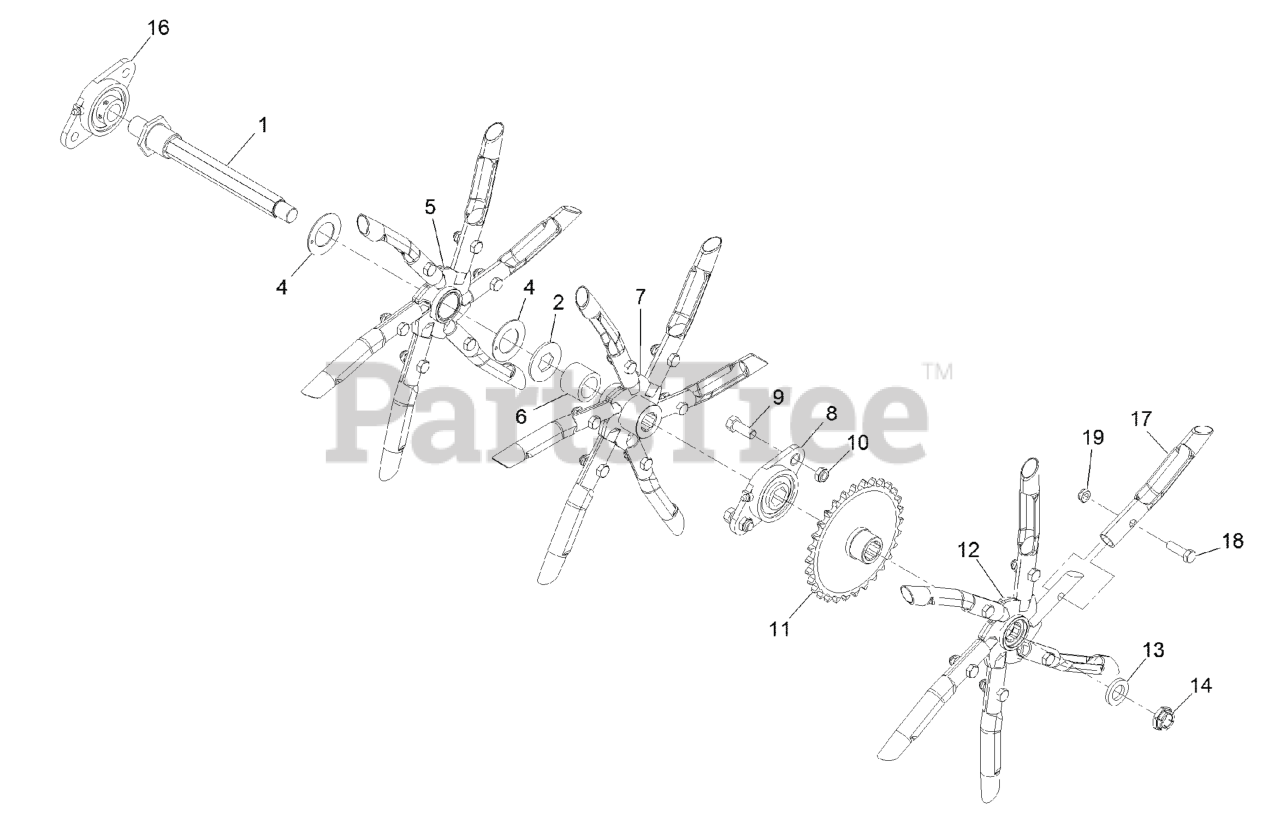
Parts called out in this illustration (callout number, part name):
1	TINE SHAFT ASM
2	KEEPER-TINE, FLOATING
4	WASHER-THRUST
5	FLOATING SPYDER ASM
6	SPACER-TINE
7	DRIVEN SPYDER ASM
8	BEARING-HEX BORE
9	SCREW-HH
10	NUT-LOCK
11	SPROCKET ASM
12	DRIVEN SPYDER ASM
13	WASHER-SPACER
14	NUT-LOCK
16	BEARING-ROUND BORE
17	TINE-CORING (3/4 INCH)
18	SCREW-HH
